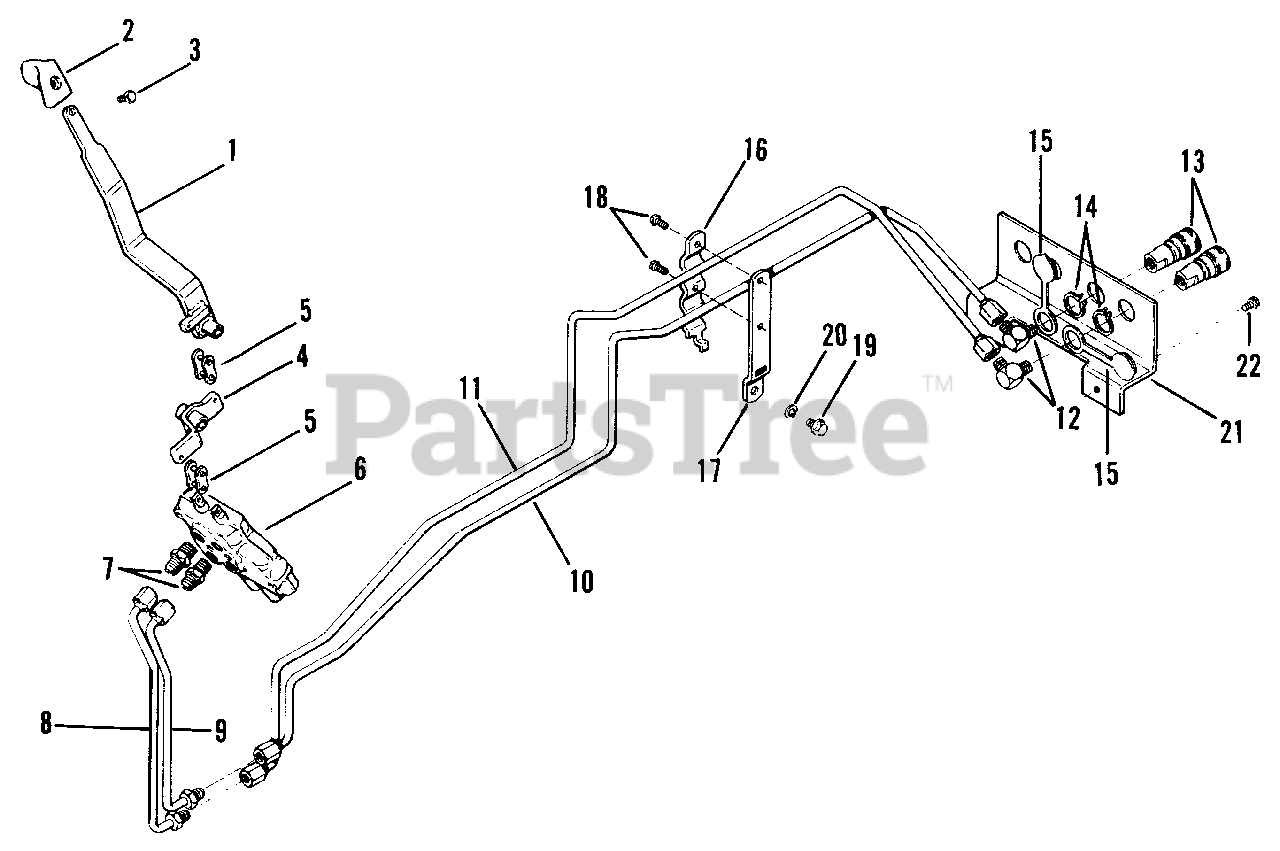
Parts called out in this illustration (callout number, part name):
1	Valve Lever Assembly
3	Screw, Taptite, 1/4"-20 x 3/4"
4	Bellcrank Assembly
5	Connector Link
7	Male Connector
8	Tube Assembly
9	Tube Assembly
10	Tube Assembly
11	Tube Assembly
13	Body Assembly
14	Retaining Ring
15	Plastic Plug
18	Screw, Taptite, 1/4"-20 x 5/8"
19	Hex Capscrew, 3/8"-16 x 5/8"
20	Lock Washer, 3/8"
21	Mounting Plate
22	Screw, Taptite, 1/4"-20 x 1/2"
